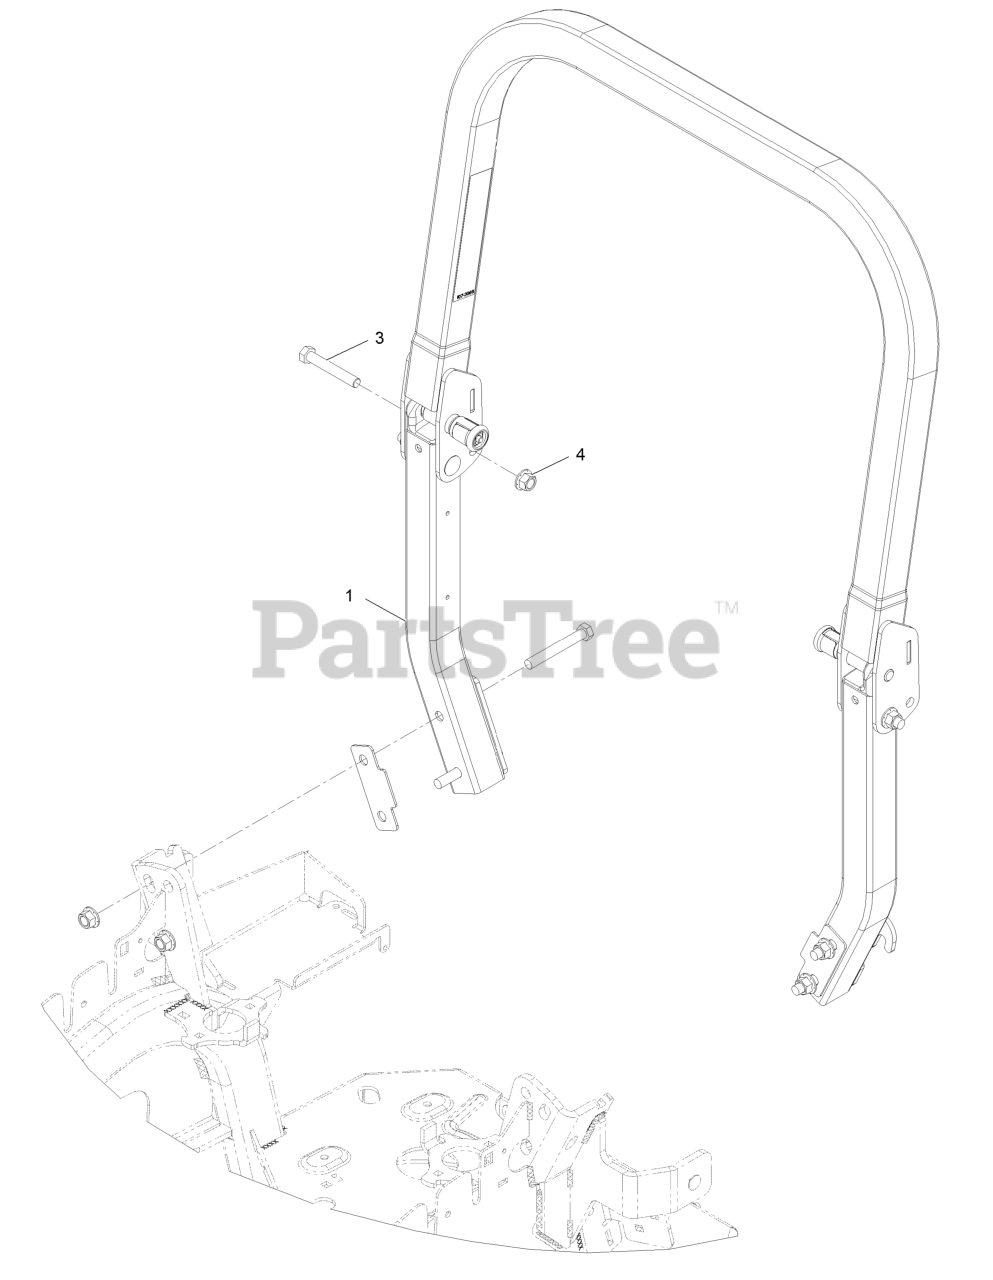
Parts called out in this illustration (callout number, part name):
1	ROPS ASM
3	Screw-HH
4	Nut-Lock
